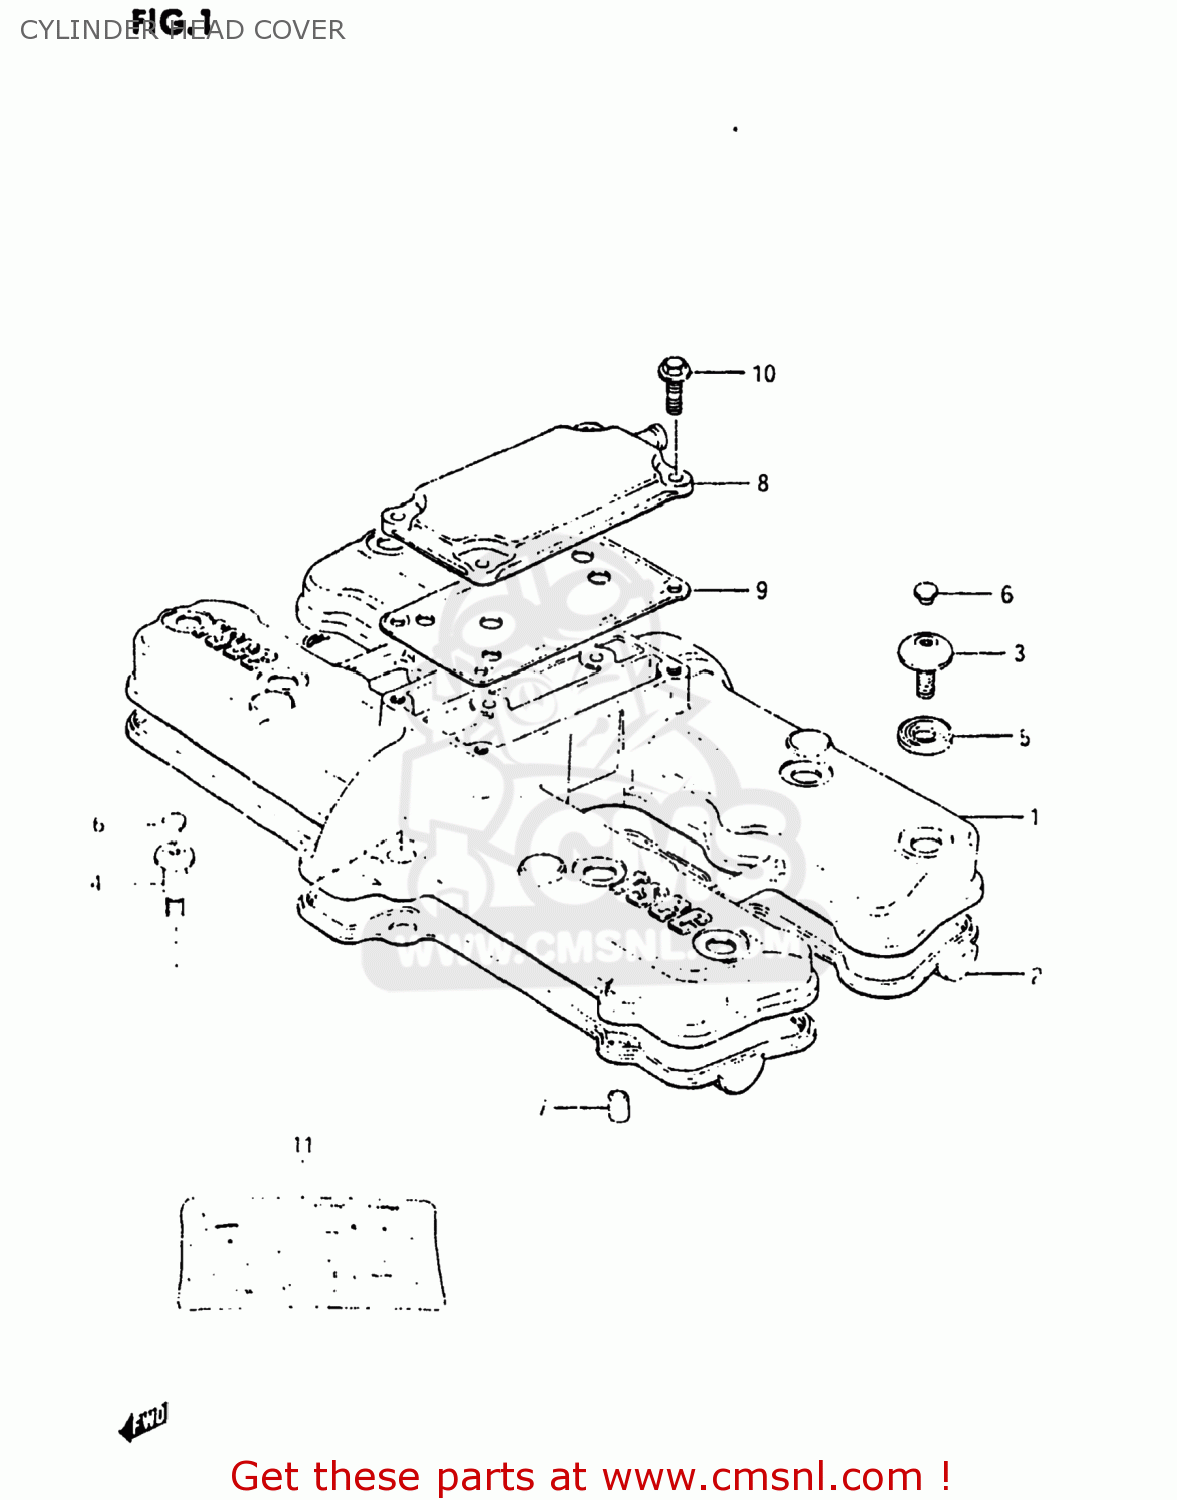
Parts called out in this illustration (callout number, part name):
1	COVER,CYLINDER HEAD
2	GASKET,HEAD COVER (NAS)
3	BOLT(7X5.5)
4	BOLT(7X19)
5	WASHER
6	CAP(OD:10)
7	PIN
8	COVER,BREATHER
9	GASKET (MCA)
10	BOLT,REAR
11	GASKET SET
